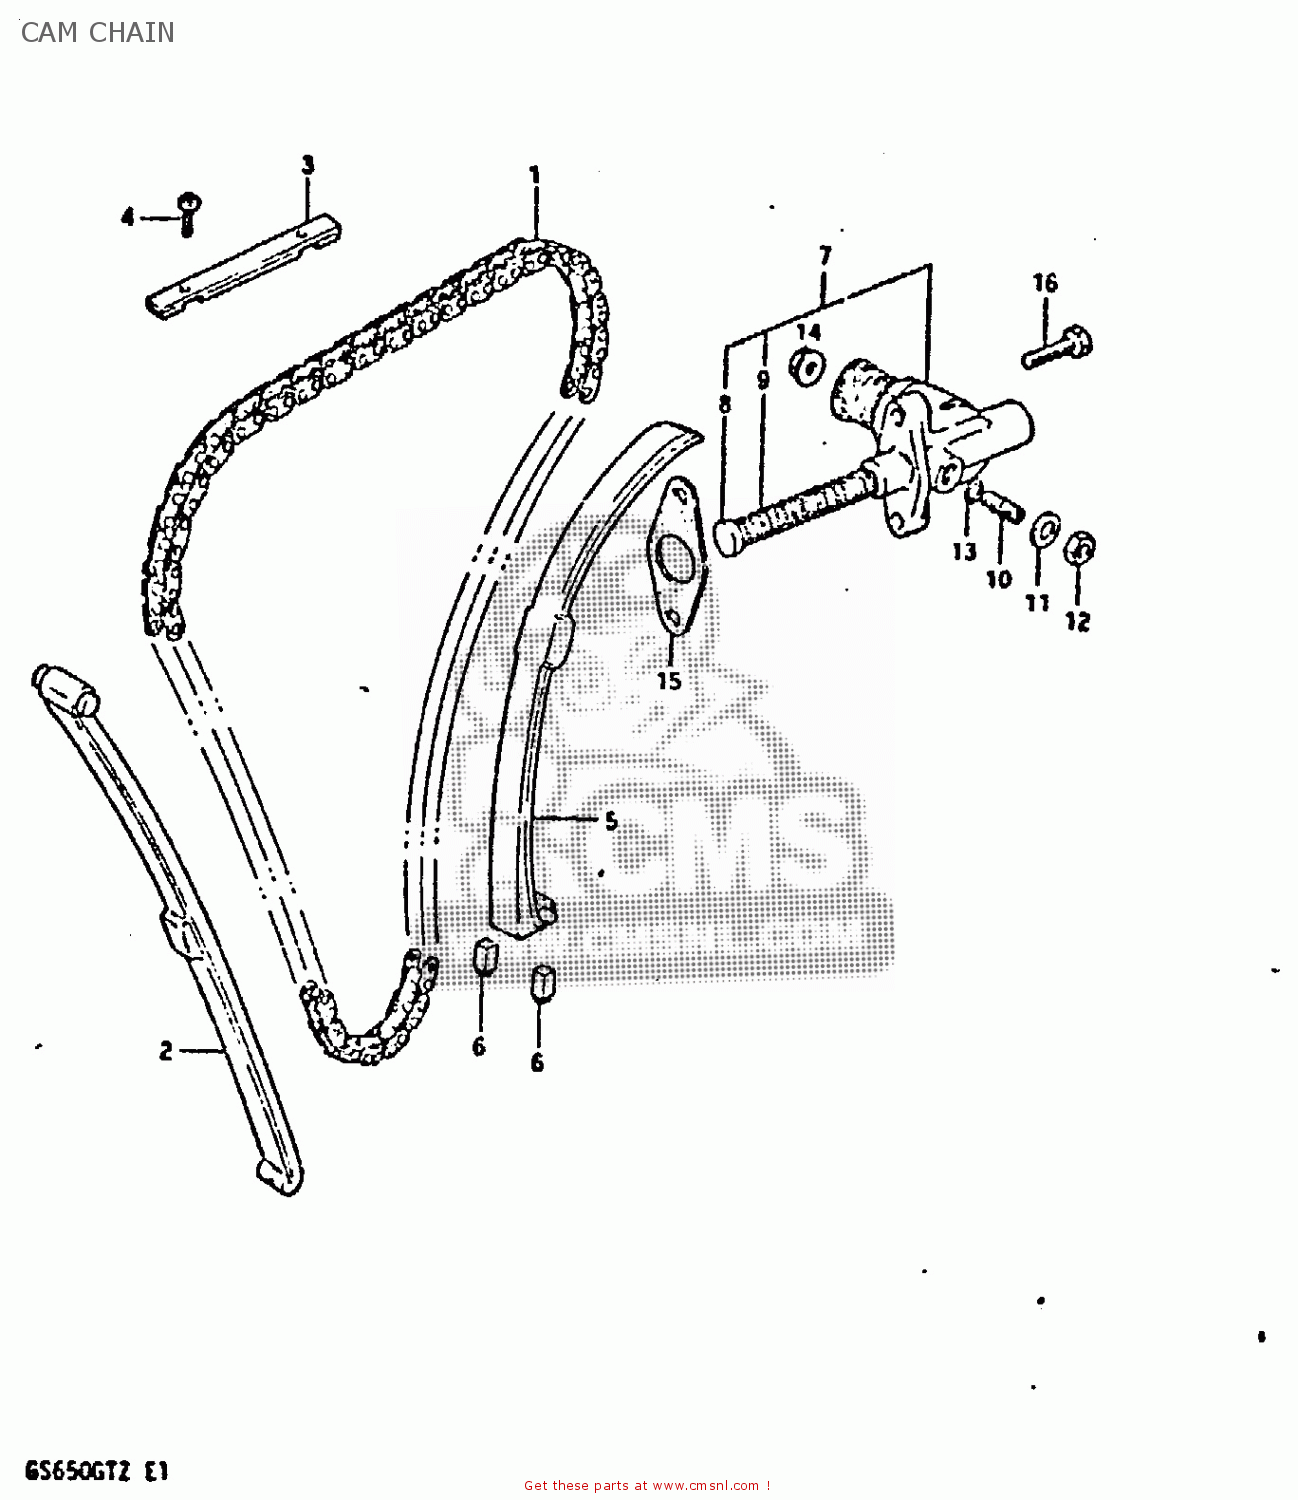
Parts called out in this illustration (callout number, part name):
1	CHAIN,CAMSHAFT DRIVE(120L)
2	GUIDE,CAM CHAIN
3	GUIDE,CAM CHAIN
4	SCREW
5	TENSIONER,CAM CHAIN
6	CUSHION,CAM CHAIN TENSIONER
7	ADJUSTER ASSEMBLY,TENSIONER
8	ROD,PUSH
9	SPRING
10	SCREW
11	WASHER
12	NUT
13	O-RING
14	NUT
15	GASKET,TENSIONER ADJUSTER (MCA)
16	SCREW (6X25)
